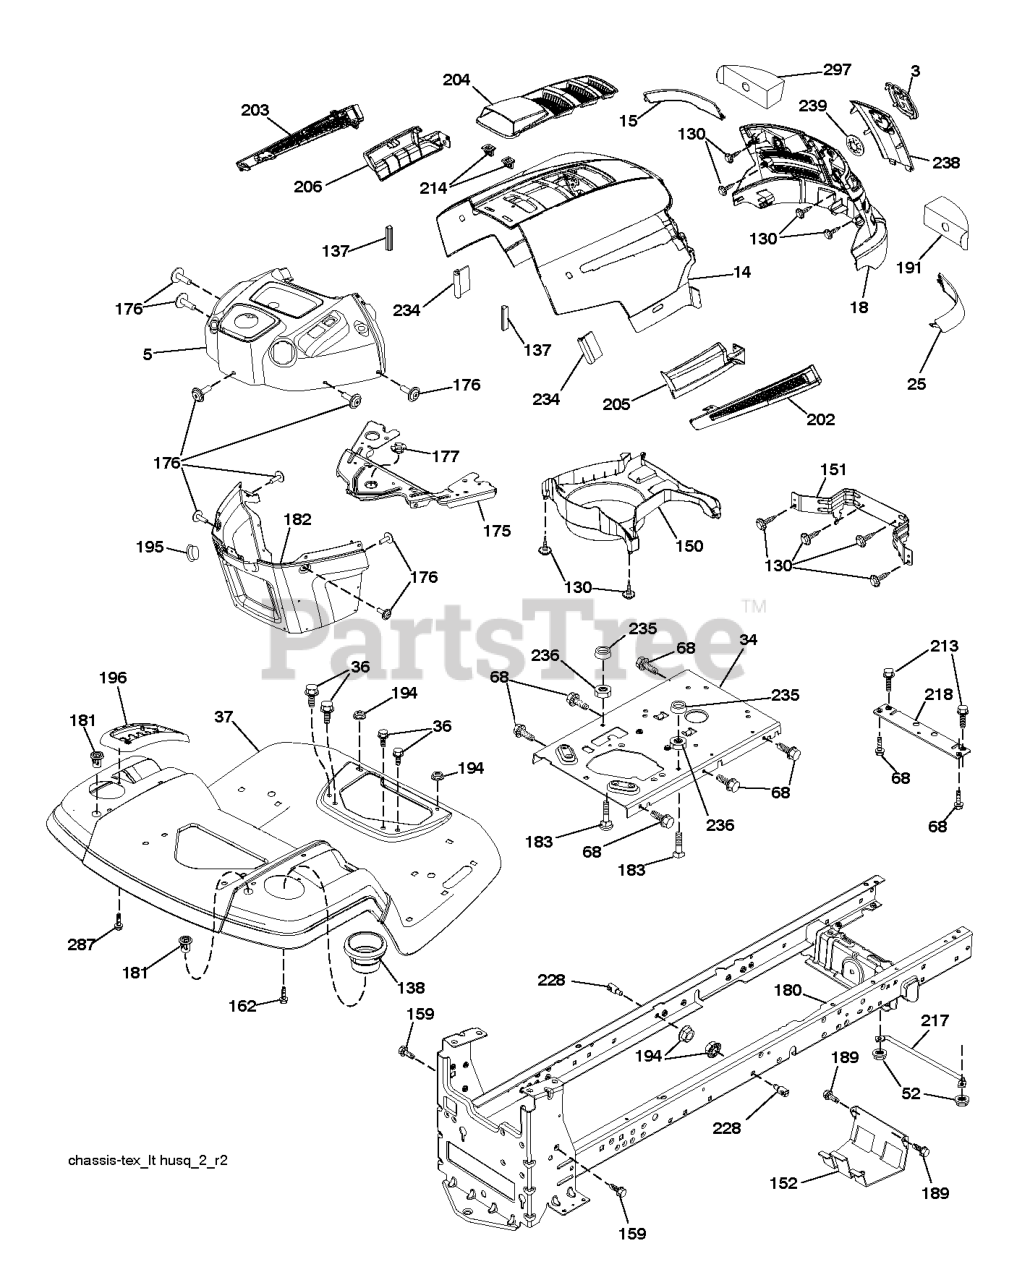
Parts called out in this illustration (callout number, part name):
3	RP LOGO
5	DASH
14	HOOD.HUSQVARNA.LT.ORANGE
15	LENS.HUSQVARNA LT.LH
18	GRILLE.SVC.HUSQVARNA.LT.GREY
25	LENS.HUSQVARNA LT.RH
34	PLATE.ENGINE.WELDED.CHASSIS
36	SCREW 5/16"
37	FENDER.TLT.FS.W/CUPHLD.ORANGE
52	LOCKNUT
68	Screw 5/16-18 x 1/2 Hex, Self Tapping 5/16-18 x 1/2
130	SCREW.#10 X 0.750.BOS
137	BUMPER DASH
138	CUPHOLDER.TL.TEX.418
151	BRACKET PIVOT
152	SHIELD.BROWNING.W/TEX
159	SCREW, 3/8-16X3/4
162	SCREW.HI-LO.CONSOLE
175	CROSSMEMBER
176	SCREW.#10-24X5/8.RN.QU
177	BUSHING STEERING
180	CHASSIS
181	BUSHING.MNT.FEND.CRGO.
182	DASH.LOWER.PREDATOR LT
183	BOLT.5/16-18X1-1/4 FULL THD
189	SCREW
191	INSERT.REFLECTIVE.RH.
194	NUT LOCK HEX FLANGE 5/16-18
195	PLUG DASH
196	RP CONSOLE.ASM.DECKLFT.GR/RBT.
204	VENT TOP HOOD
213	BOLT
214	CLIP.RETAINER.TINNER.
217	ROD.PIVOT.HOOD
218	X-PIECE.HOOD.STOP.NON/
228	STUD.FASTNER.W/ANTI-ROTATE
234	BUMPER.HOOD.TEX.HUSQVARNA
235	SPACER FENDER
236	NUT.CENTERLOCK.5/16-
238	TRIM
287	SCREW 1/4X20
297	INSERT REFLECTIVE
